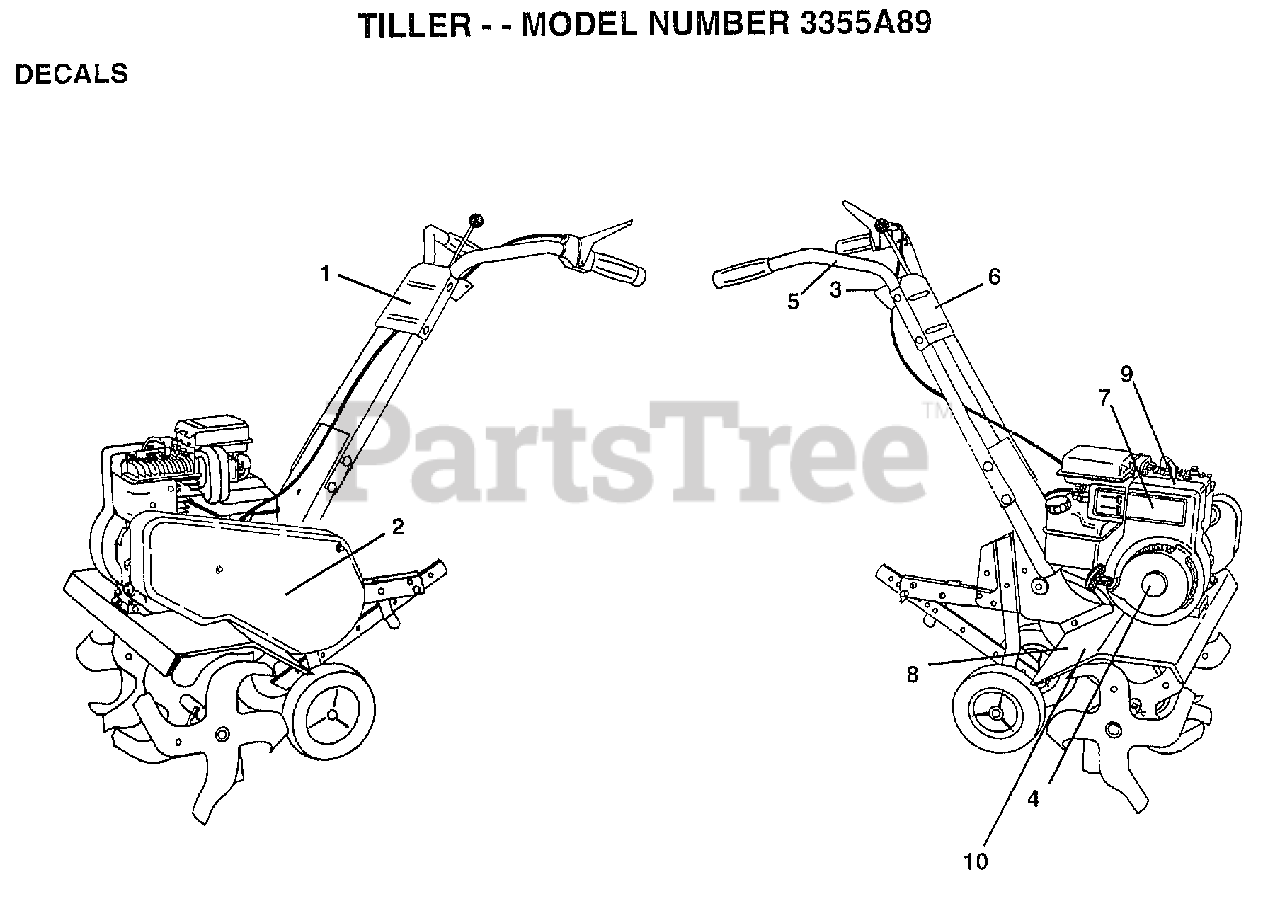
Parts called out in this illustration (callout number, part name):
1	DECAL.CNTRL.PNL.5
2	DECAL.BELT.GUARD
3	DECAL REVERSE
5	DECAL TI
6	DECAL-SERVICE REV. PANEL WIZARD
7	DECAL, BRIGGS & STRATTON
8	DECAL TI
10	DECAL.TINE.SHIELD
